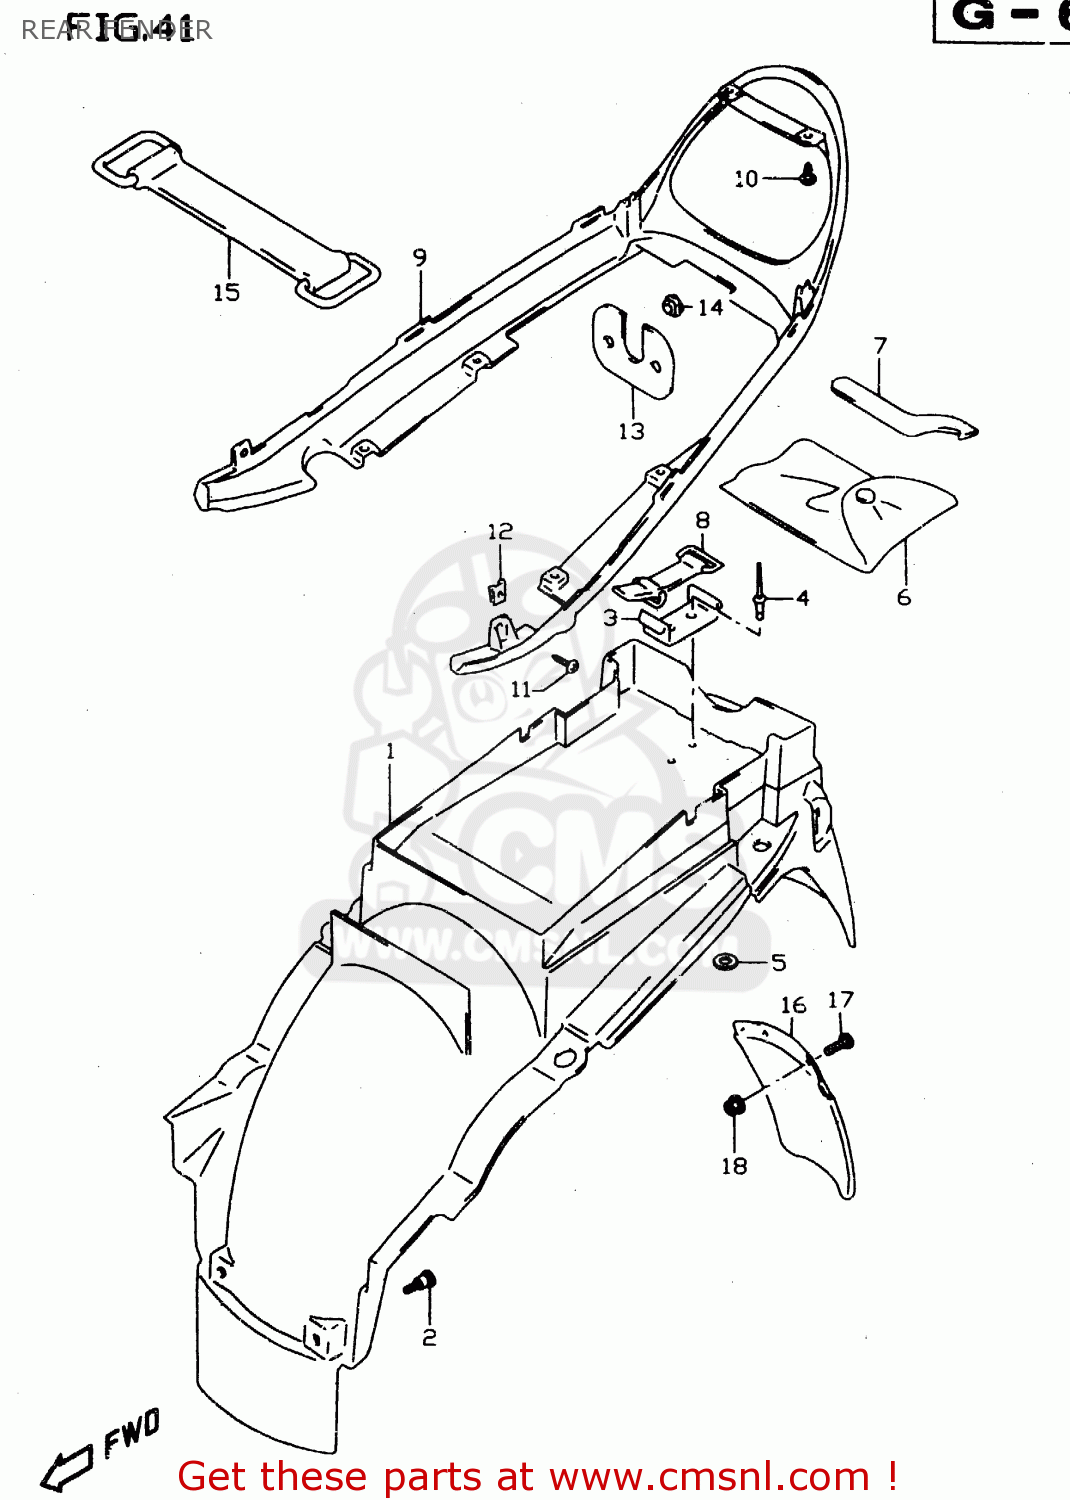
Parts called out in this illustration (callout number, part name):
1	FENDER,RR LWR
2	BOLT(6X16)
3	HOLDER,TOOL
4	RIVET
5	WASHER
6	TOOL ASSY
7	CLAMP
8	BAND,TOOL
9	FENDER,RR UPR
10	SCREW
11	SCREW
12	NUT
13	MUDGUARD,RR FENDER RR
14	CUSHION,RR FENDER
15	BAND
16	EXTENSION,RR FENDER
17	SCREW
18	NUT
